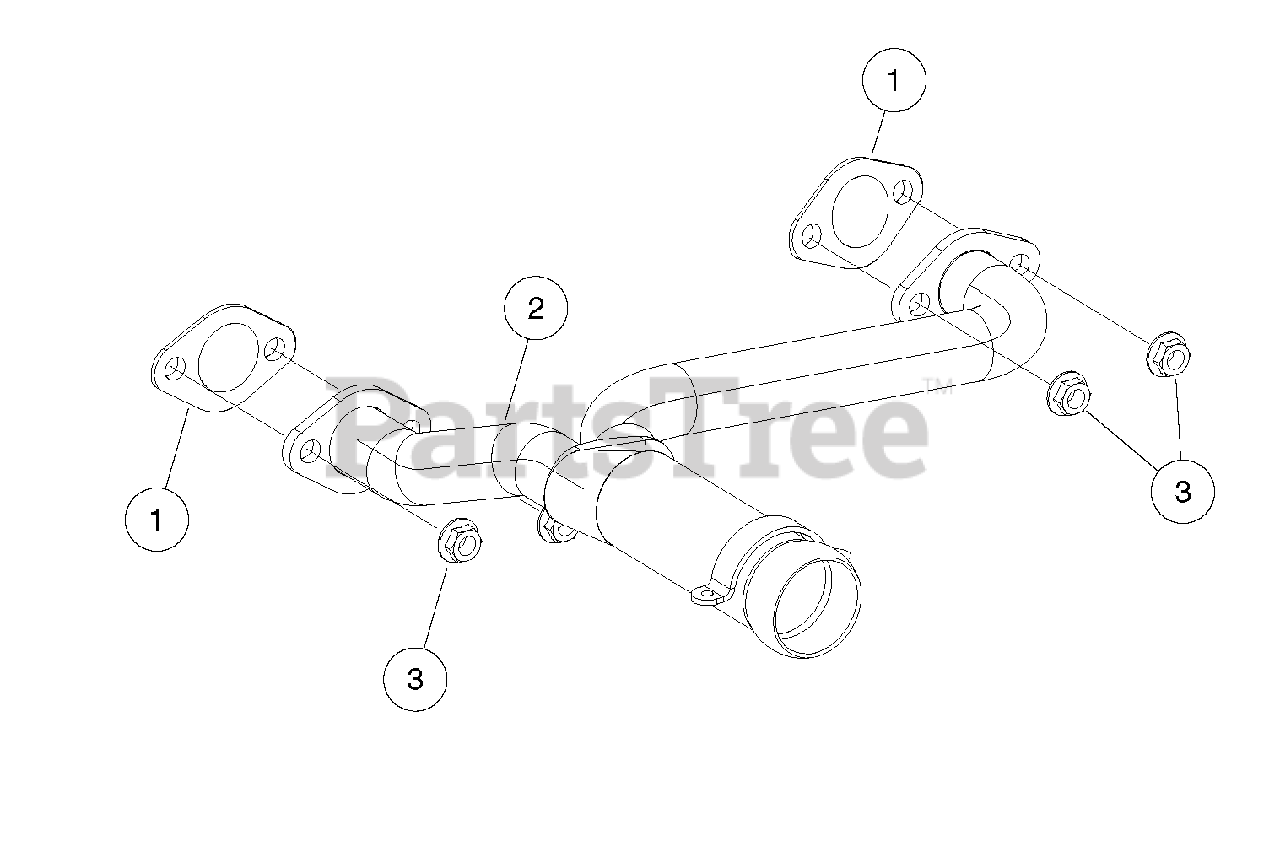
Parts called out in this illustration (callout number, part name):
1	Gasket, Exhaust Header, Fh680d
2	Header, Exhaust, Gas, Fh680d
3	Nut Flg, M8 X 1.25 Serrated
